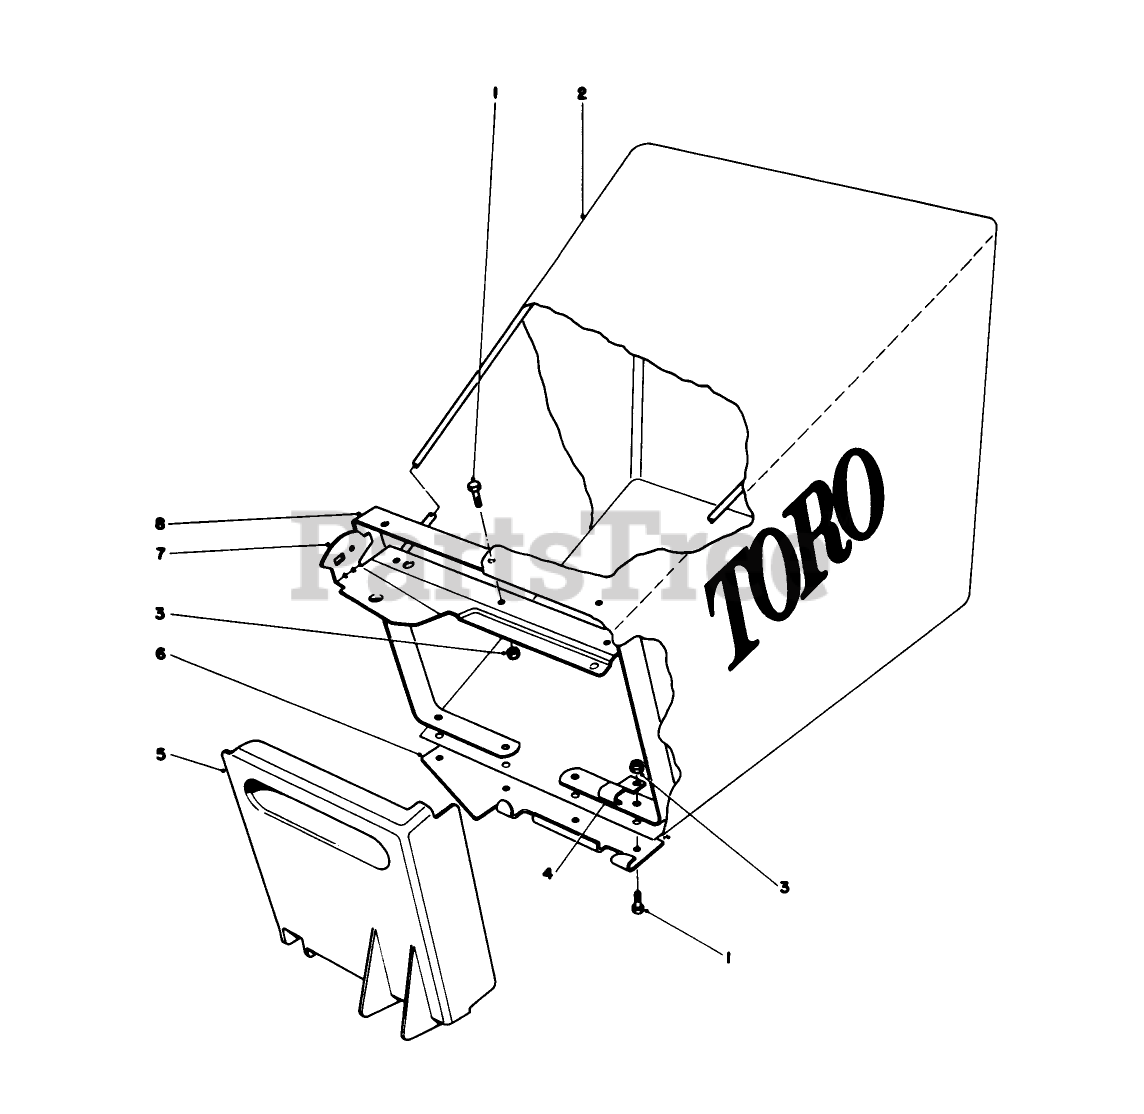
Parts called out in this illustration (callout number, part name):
1	SCREW-HWH
5	BAG DOOR
7	BAG FRAME ASM
8	LOWER BAG FRAME
